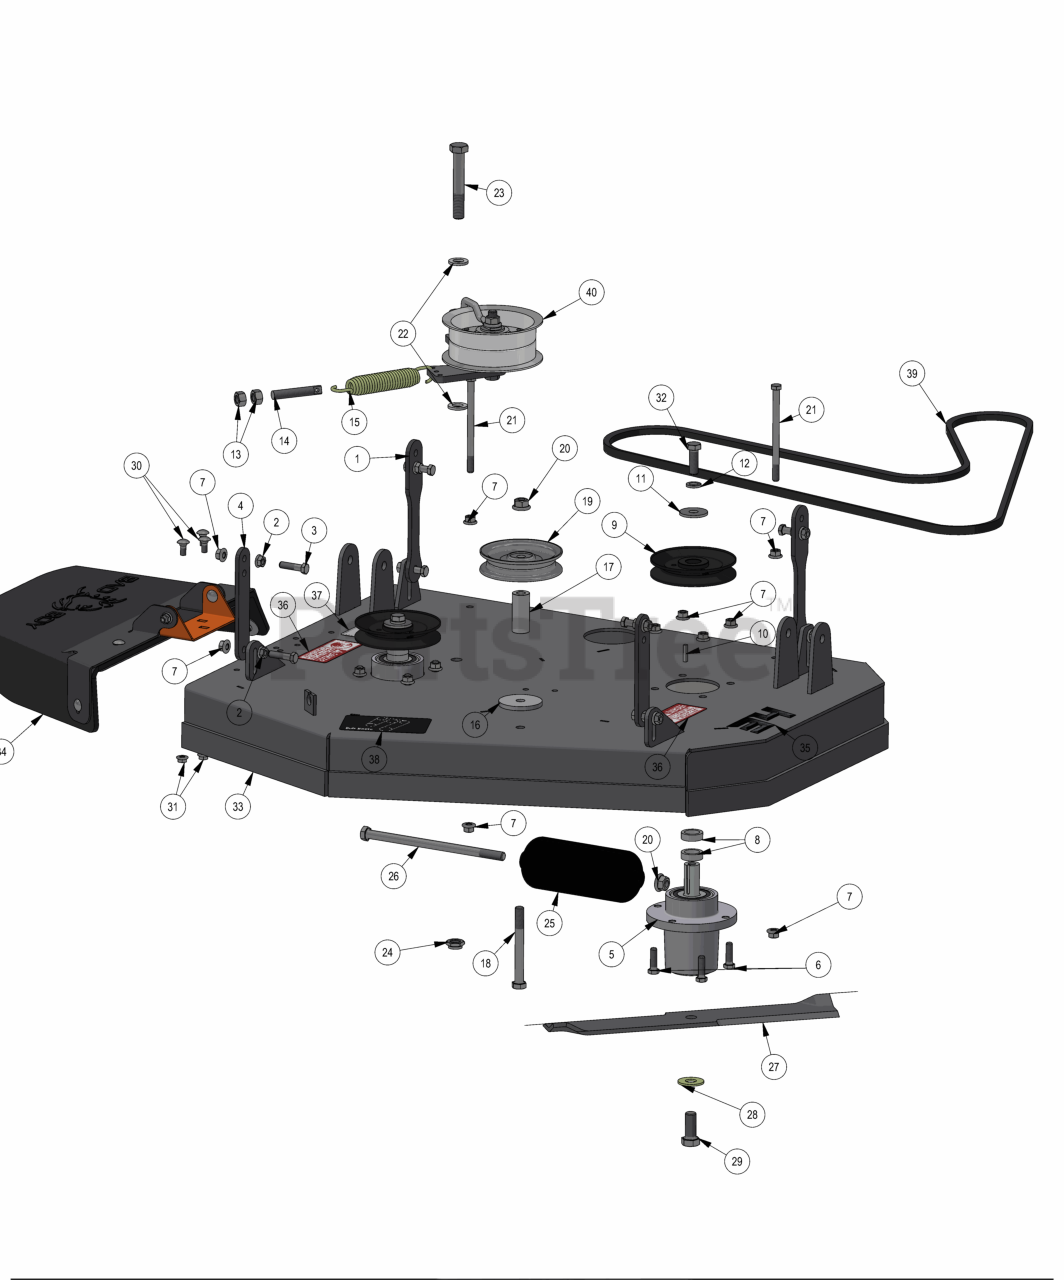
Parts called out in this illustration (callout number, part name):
1	2019 Stand-On Rear Deck Hanger
2	3/8-16 HEX SERRATED FLANGE NUT HARD/ZINC
3	3/8-16 X 1-1/2 HEX CAP SCREW (GR.5) ZINC
4	2019 Revolt Front Deck Hanger
5	36'' Revolt Spindle Assembly
6	3/8-16 X 1-1/4 HEX CAP SCREW (GR.5) ZINC
7	3/8-16 NYLON INSERT FLANGE LOCKNUT (GR.F) ZINC
8	36 Deck Spindle Spacer
9	MZ Deck Pulley
10	3/16 X 1 SQ MACHINERY KEY 1018 STL ZINC
11	1/2 BELLEVILLE WASHER (1-5/8 OD X .140 THK) ZINC
12	1/2 SPLIT LOCKWASHER (GR.8) ZINC/YELLOW
13	1/2-13 HEX NUT ZINC
14	All Thread
15	Deck Idler Spring
16	MZ Deck Idler Spacer
17	2019 Revolt Stationary Idle Spacer
18	1/2-13 X 4-1/2 HEX CAP SCREW (GR.5) ZINC
19	5 V Idler Pulley 1/2" Bore
20	1/2-13 NYLON INSERT FLANGE LOCKNUT ZINC
21	3/8-16 X 5-1/2 HEX CAP SCREW (GR.5) ZINC
22	.635 ID X 1.120 OD X .140 THICK FLAT WASHER NYLON
23	5/8-11 X 4 HEX CAP SCREW (GR.8) ZINC YELLOW
24	5/8-11 NYLON INSERT JAM LOCKNUT ZINC
25	3in deck roller
26	1/2-13 X 9 HEX CAP SCREW (GR.5) ZINC
27	34'' DeckBlade
28	5/8'' Flat Washer
29	5/8-18 X 1-1/2 HEX CAP SCREW (GR.8) ZINC YELLOW
30	5/16-18 x 3/4 Carriage Bolt
31	5/16-18 HEX SERRATED FLANGE NUT HARD/ZINC
32	1/2-20 X 1-1/2 HEX CAP SCREW (GR.5) ZINC
33	2024 34 Stand On Deck Weldment
34	MZ Discharge Chute Assembly
35	34" Deck Decal
36	Danger Decal-Spindle/Discharge
37	Deck Impact Patent Decal 9591803
38	36" Revolt Deck Belt Route Decal
39	34'' deck belt 94.25''
40	SD Deck Idler Assembly
